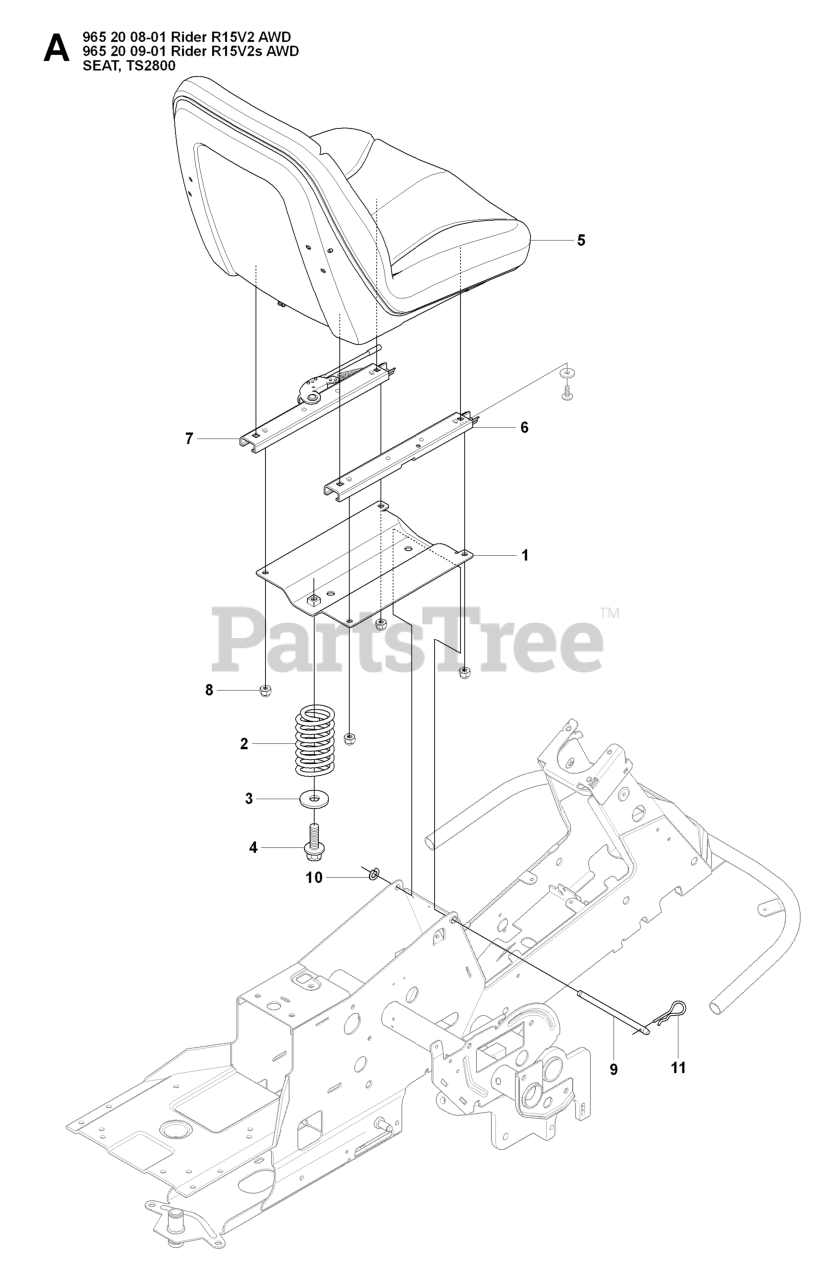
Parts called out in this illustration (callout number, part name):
2	SEAT SPRING
4	Screw M10x25
5	SEAT
8	LOCKNUT M8
10	RETAINING RING SGA 10
